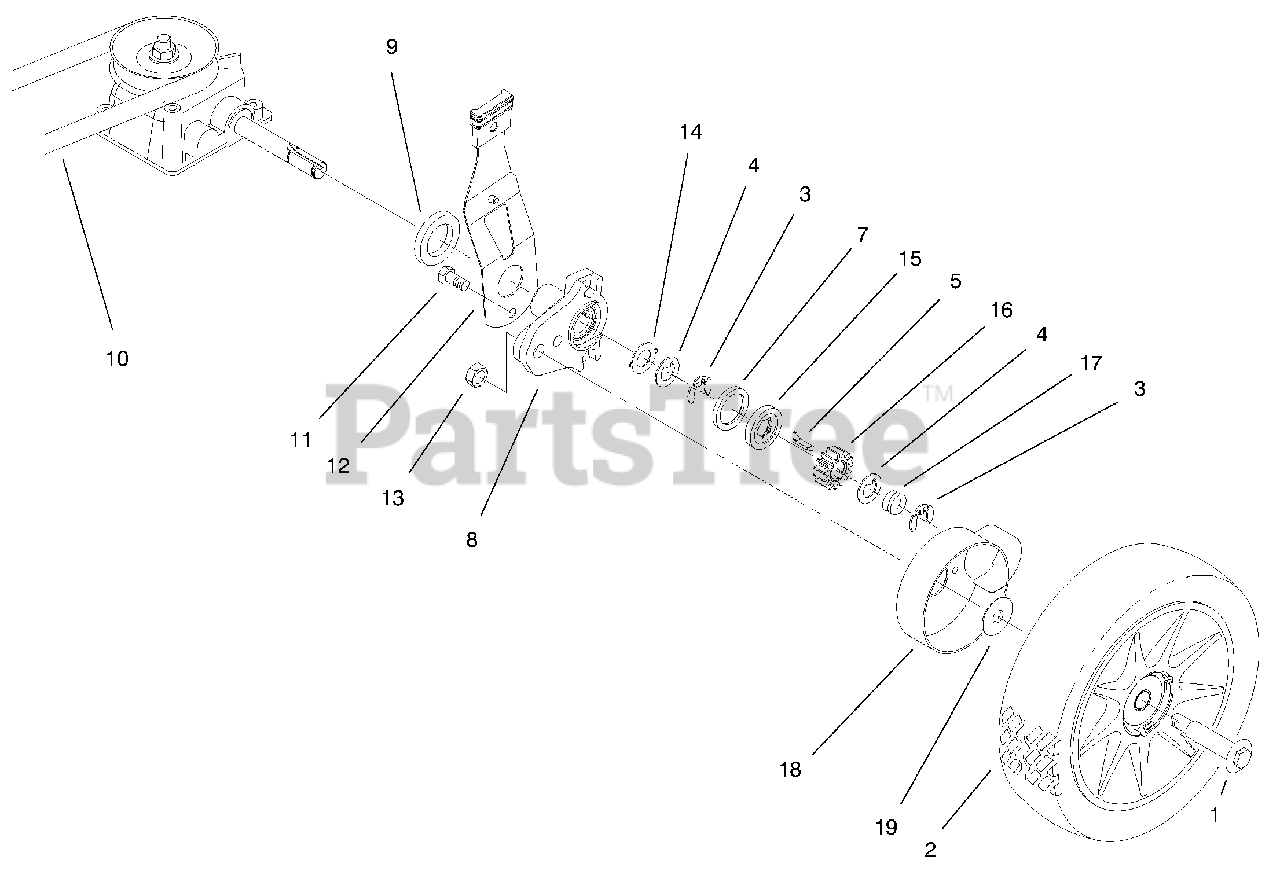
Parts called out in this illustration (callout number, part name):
1	Bolt-Shoulder
3	Ring-Retaining
4	Washer-Thrust
5	Key-Rocking LH
7	Ring-Friction
8	ASM-Hgt Adj Arm
9	Spacer-Axle Shaft
12	ASM-Spring Arm
13	Nut-Lock
14	Washer-Thrust
16	Gear-Pinion
17	Spring-Compression
18	Cover-Wheel
19	Washer-Stepped
